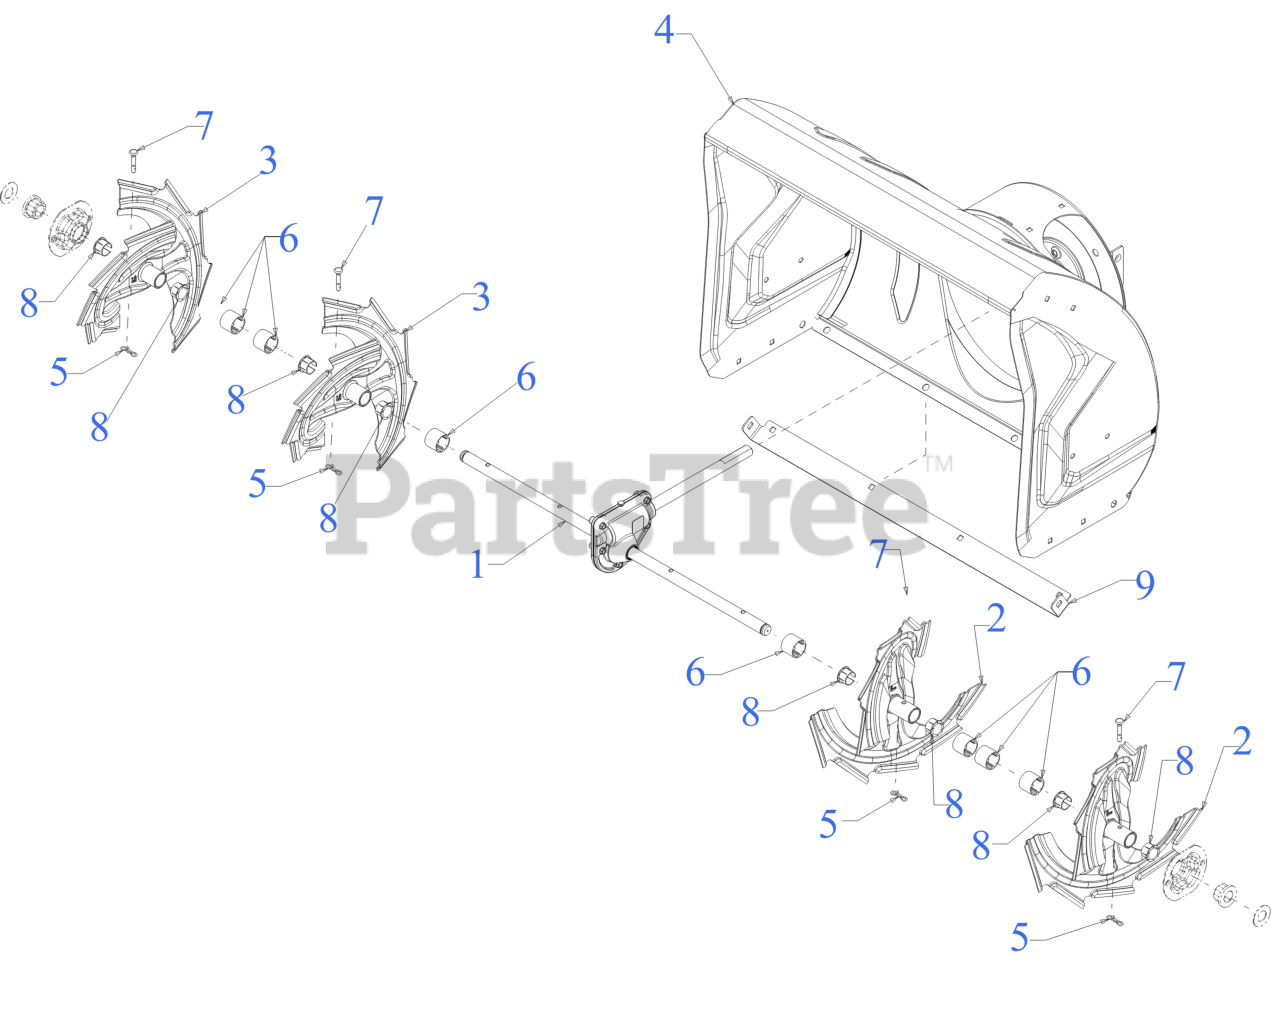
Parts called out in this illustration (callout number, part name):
1	GEARBOX ASSEMBLY 28"
2	10T AUGER SPIRAL (LH)
3	10T AUGER SPIRAL (RH)
4	28" AUGER HOUSING
5	BOW TIE COTTER PIN 1/4-5/16
6	SPACER 1.25OD x .75ID X1.00 LG
7	SHEAR PIN .25 x 1.50 GR2
8	FLANGE BUSHING
9	28" SHAVE PLATE
